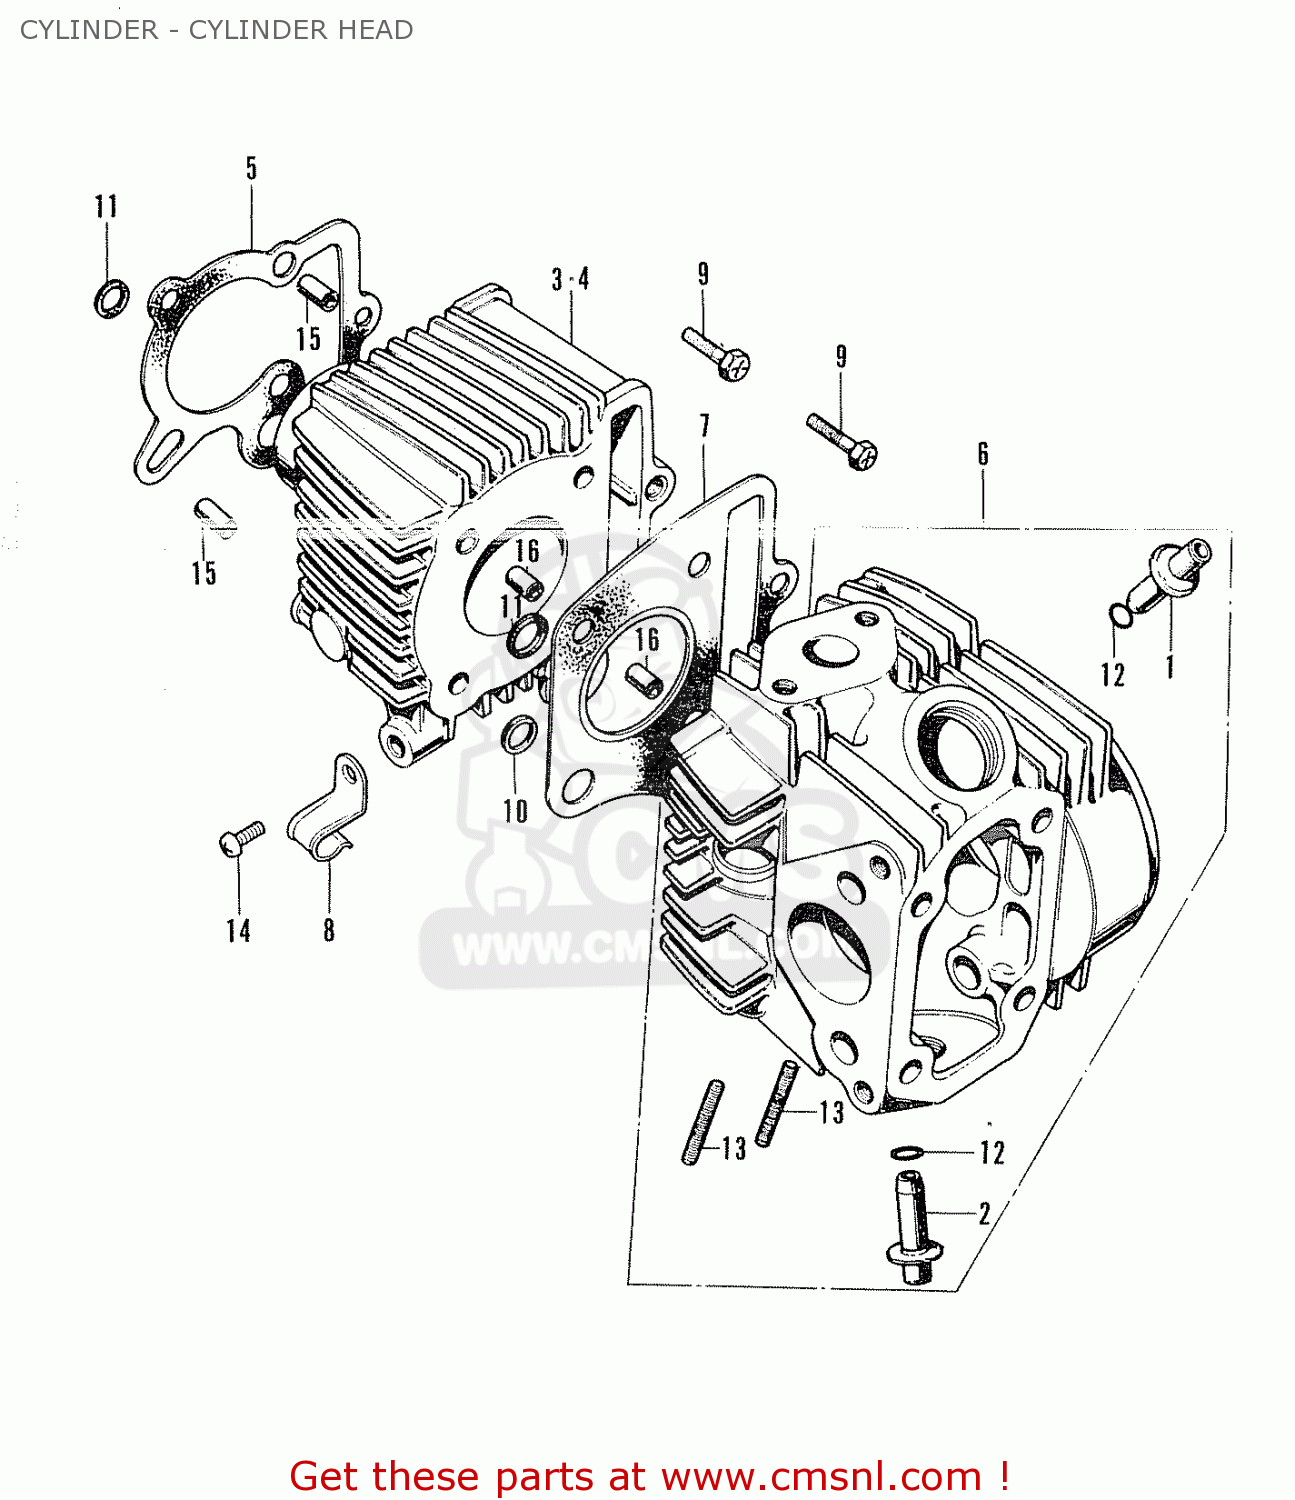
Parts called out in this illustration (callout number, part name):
1	GUIDE, IN. VALVE
2	GUIDE,EXH-VALVE
3	CYLINDER
5	GASKET,CYLINDER (MCA)
6	HEAD,CYLINDER
7	GASKET,CYLN.HEAD (MCA)
9	BOLT, 6M/M
10	GASKET 7.5 RUBBER
11	PACKING,RUB.16M/M
12	O RING 9.5X1.6
13	BOLT,STUD 6X32
15	PIN,KNOCK 8X12A
